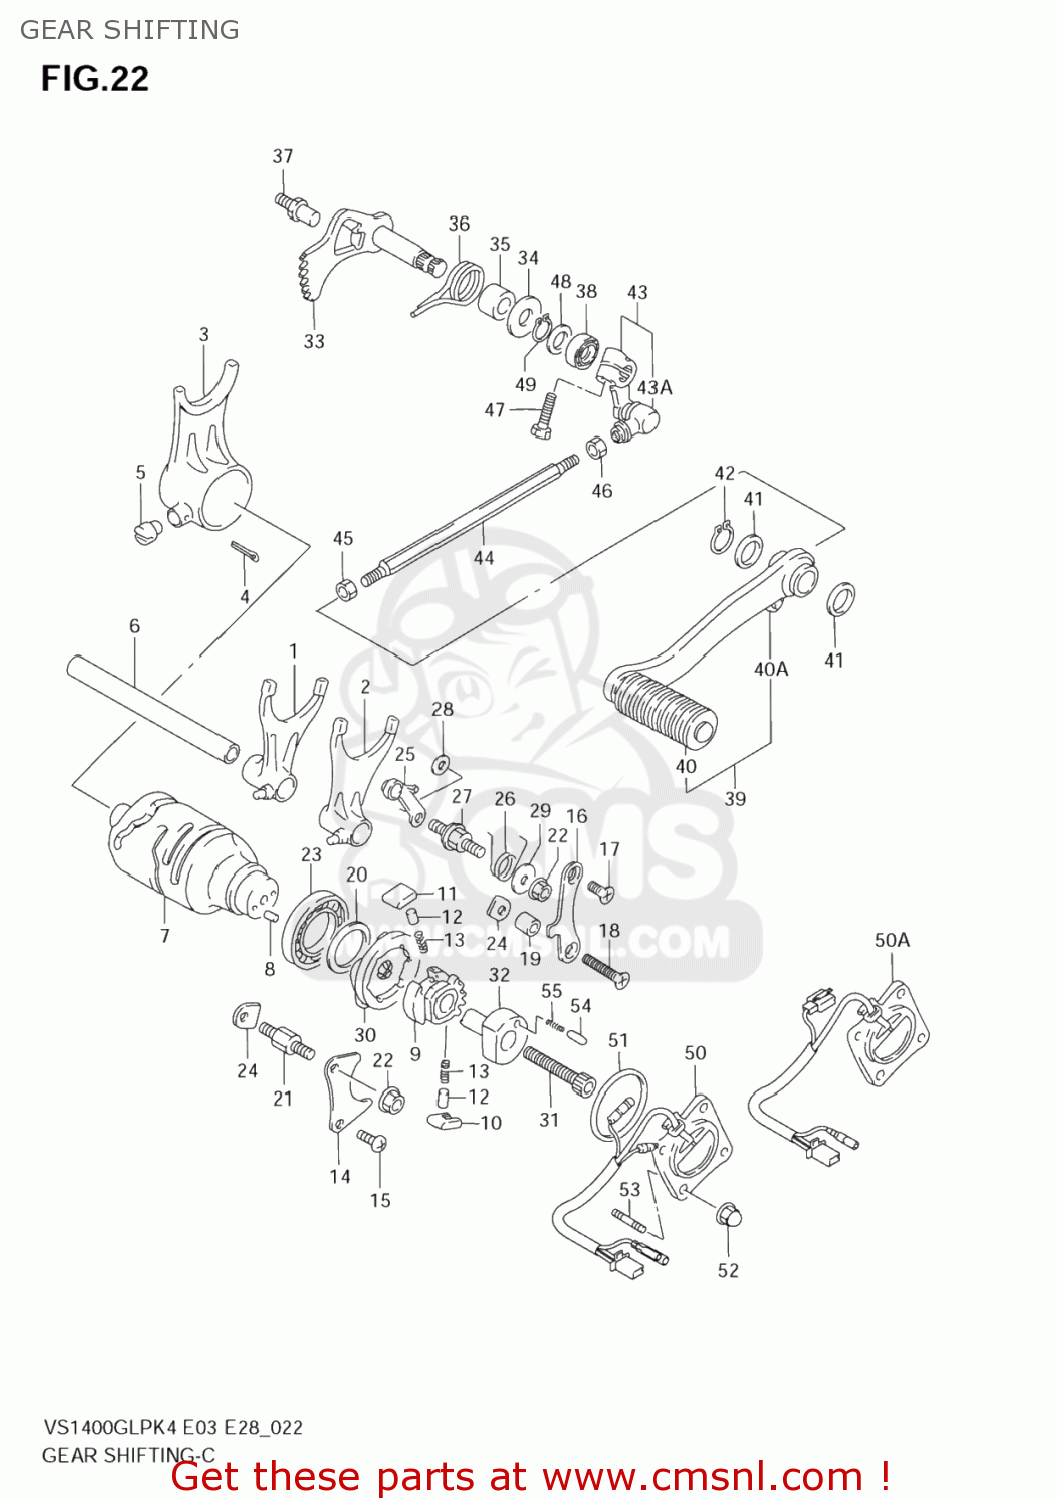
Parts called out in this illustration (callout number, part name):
1	FORK,GEAR SHIFT NO.1
2	FORK,GEAR SHIFT NO.2
3	FORK,GEAR SHIFT NO.3
4	PIN
5	PIN
6	SHAFT,GEAR SHIFT FORK(L:152)
7	CAM,GEAR SHIFT
8	PIN
9	GEAR,GEAR SHIFT CAM DRIVEN
10	PAWL,GEAR SHIFT NO.1
11	PAWL,GEAR SHIFT NO.2
12	PIN(5X8)
13	SPRING
14	LIFTER,GEAR SHIFT POLE
15	BOLT(6X12)
16	GUIDE,GEAR SHIFT CAM
17	SCREW(6X12)
18	SCREW(6X30)
19	SPACER(6.5X10X14)
20	WASHER(25X32X3)
21	BOSS,SHIFT POLE LIFTER
22	NUT
23	BEARING(25X47X8)
24	RETAINER
25	STOPPER,GEAR SHIFT CAM
26	SPRING
27	SUPPORT,CAM STOPPER ARM
28	WASHER
29	WASHER(6.5X18X2)
30	PLATE,GEAR SHIFT CAM
31	BOLT(6X50)
32	HOLDER,NEUTRAL SWITCH
33	SHAFT,GEAR SHIFT
34	WASHER(12.5X28X1.2)
35	SPACER(12X20X15.3)
36	SPRING
37	STOPPER,SHIFT ARM
38	OIL SEAL
39	LEVER ASSY,GEAR SHIFT
40	RUBBER,GEAR SHIFT PEDAL
40A	COVER,DUST
41	WASHER(14.5X22X1)
42	CIRCLIP
43	ARM,GEAR SHIFT LINK
43A	COVER,DUST
44	ROD,GEAR SHIFT LINK
45	NUT
46	NUT
47	BOLT
48	SHIM(12X20X1)
49	CIRCLIP
50	BASE ASSY,NEUTRAL SW TERMINAL
50A	BASE ASSY,NEUTRAL SW TERMINAL
51	O RING(D:2.4,ID:35.5)
52	NUT
53	BOLT,STUD
54	PIN
55	SPRING
